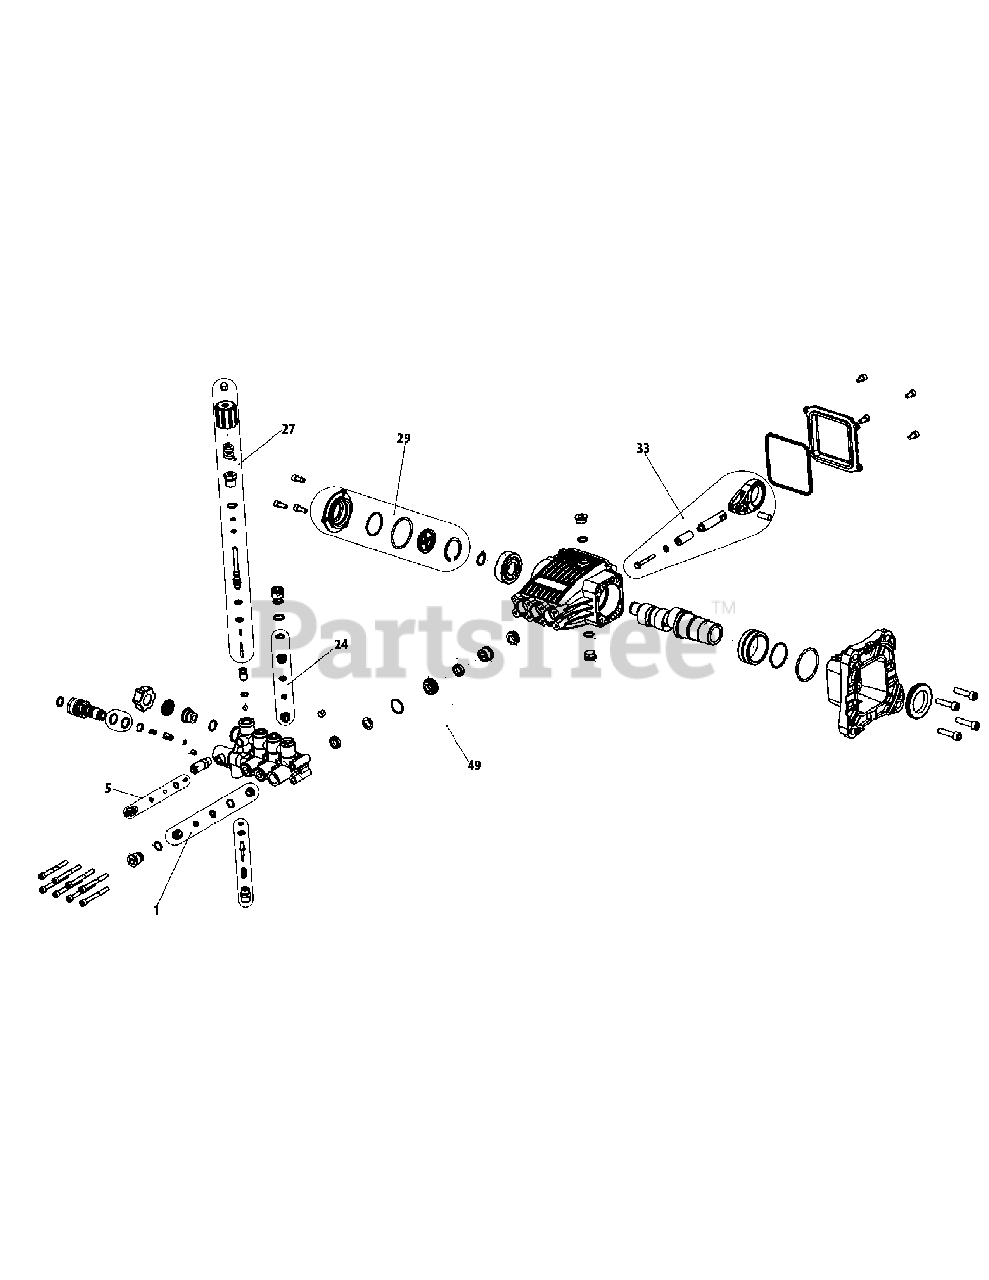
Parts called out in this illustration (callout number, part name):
1	Valve Kit-Outlet Manfld
5	Injector Kit-Soap
24	Valve Kit-Inlet Manfld
27	Unloader Kit-Manifold
29	Cover Kit-Crnkcase Side
33	Rod Kit-Connecting
49	Seal Kit-Hi/Lo Pressure
51	Valve Kit-Pressure Boost
